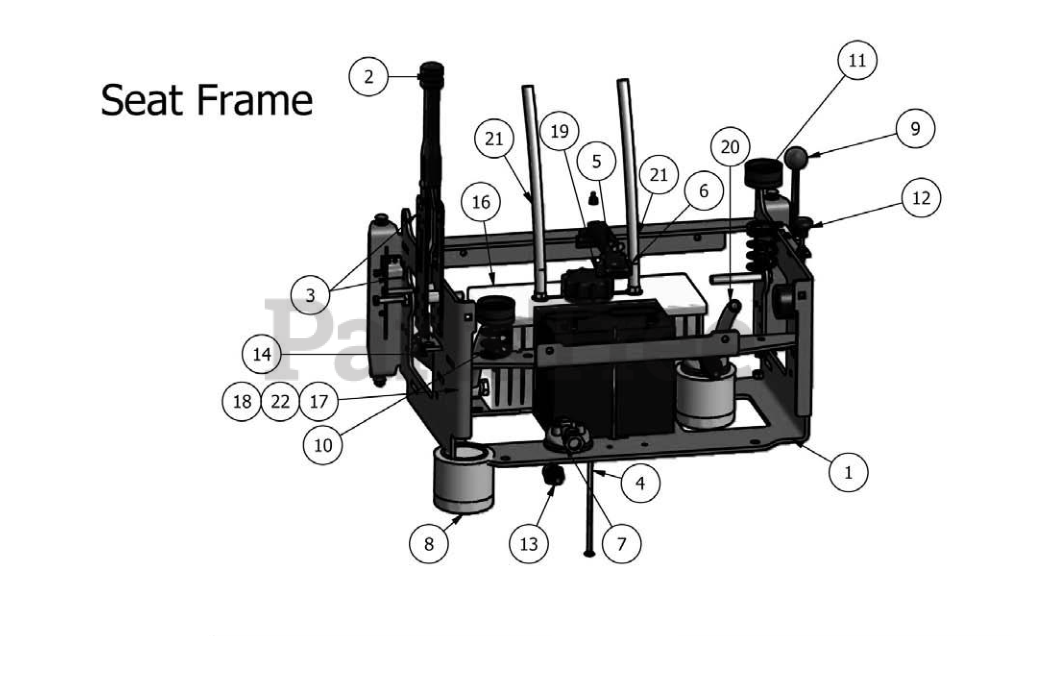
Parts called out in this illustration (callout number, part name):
1	Seat Frame
2	Brake Lever
3	Safety Switch
4	8" Stove Bolt
5	1/4" Wing Nut
6	Battery Hold-Down
7	Filter Head
8	Hydraulic Filter
10	Seat Spring
11	Seat Bumper
13	Filter Head Fitting
14	Brake Cable Short
15	Brake Cable Long
16	Aluminum Hydraulic Tank
17	3/8" x 1 1/4" Hex Bolt
18	3/8" Flange Nut
19	Hydraulic Tank Cap
20	1/2" x 9 1/4" Braided Hose
21	3/8" x 32" Clear Hose
22	3/8" Flat Washer
